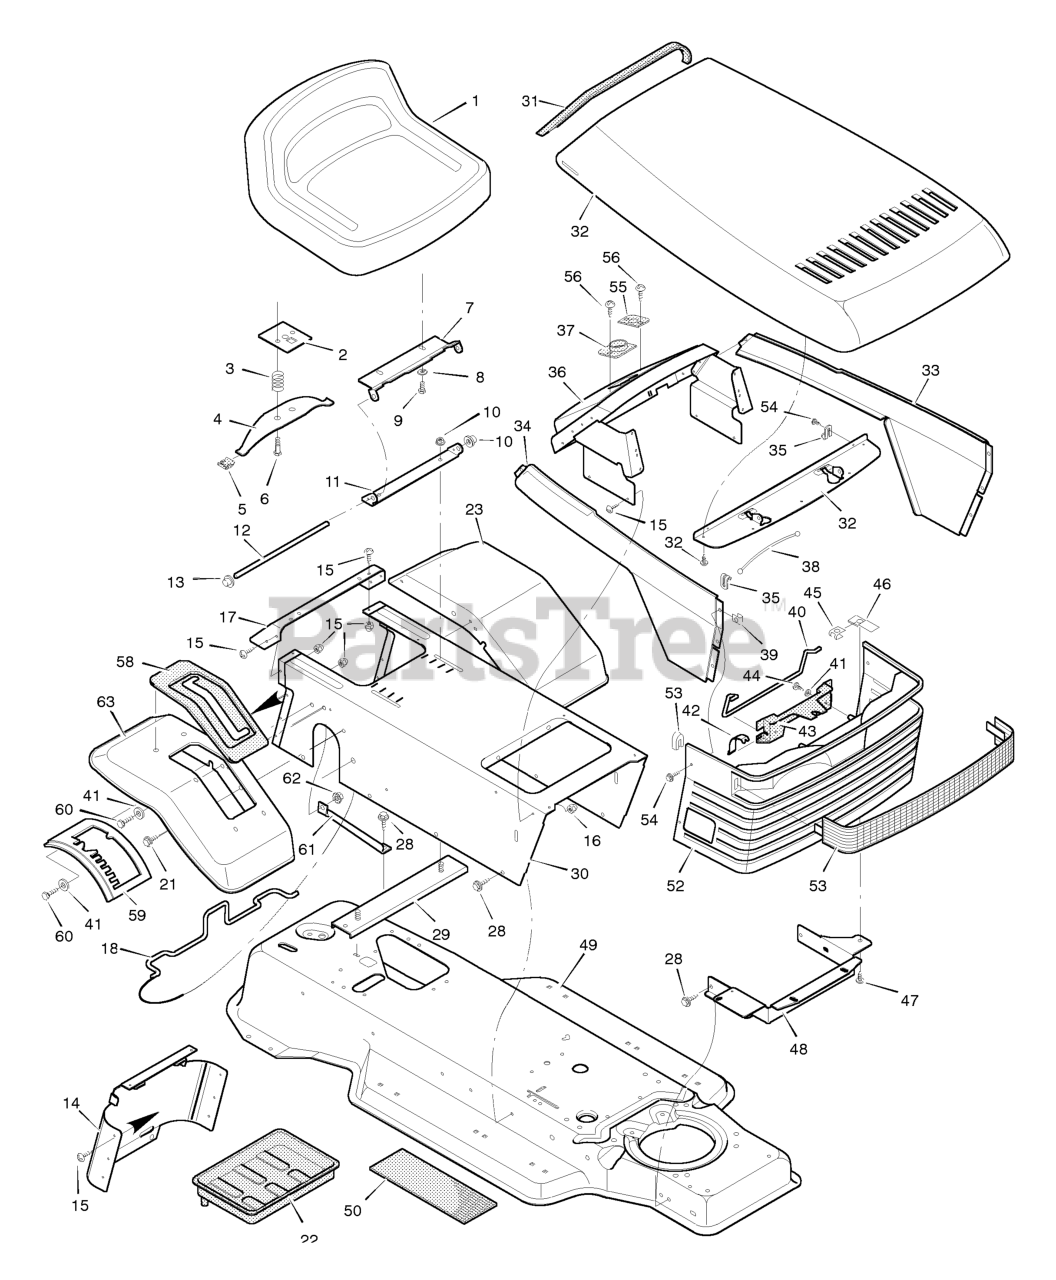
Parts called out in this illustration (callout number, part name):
2	Plate Assembly, Switch
3	Spring, Compression
4	Spring, Seat
5	Glide, Spring
6	Bolt, Shoulder
7	Support, Seat
8	Lockwasher
9	Bolt, Hex
10	Locknut, Flange
11	Bracket, Pivot
12	Rod, Pivot
13	Cap, Push On
14	Cap, Console
15	Screw
16	Locknut
17	Fender, Apron
18	Clamp, Battery
22	Tray, Battery
29	Channel Assembly
31	Trim, Edge
32	Hood Assembly
33	Panel, Left
34	Panel, Right
35	Clip, Cable
36	Dash Assembly
37	Bearing, Steering
39	U- Fastener
40	Rod, Hinge
41	Washer
42	Spring, Hood
43	Bracket, Hood Mount
45	Nut, Speed
46	Shield, Heat
48	Support, Grille
49	Frame Assembly
53	Lens
55	Bearing
58	Cover, Shift
59	Gate, Shift
60	Bolt, Hex
61	Strut, Shifter
62	Locknut
63	Fender, SOG
